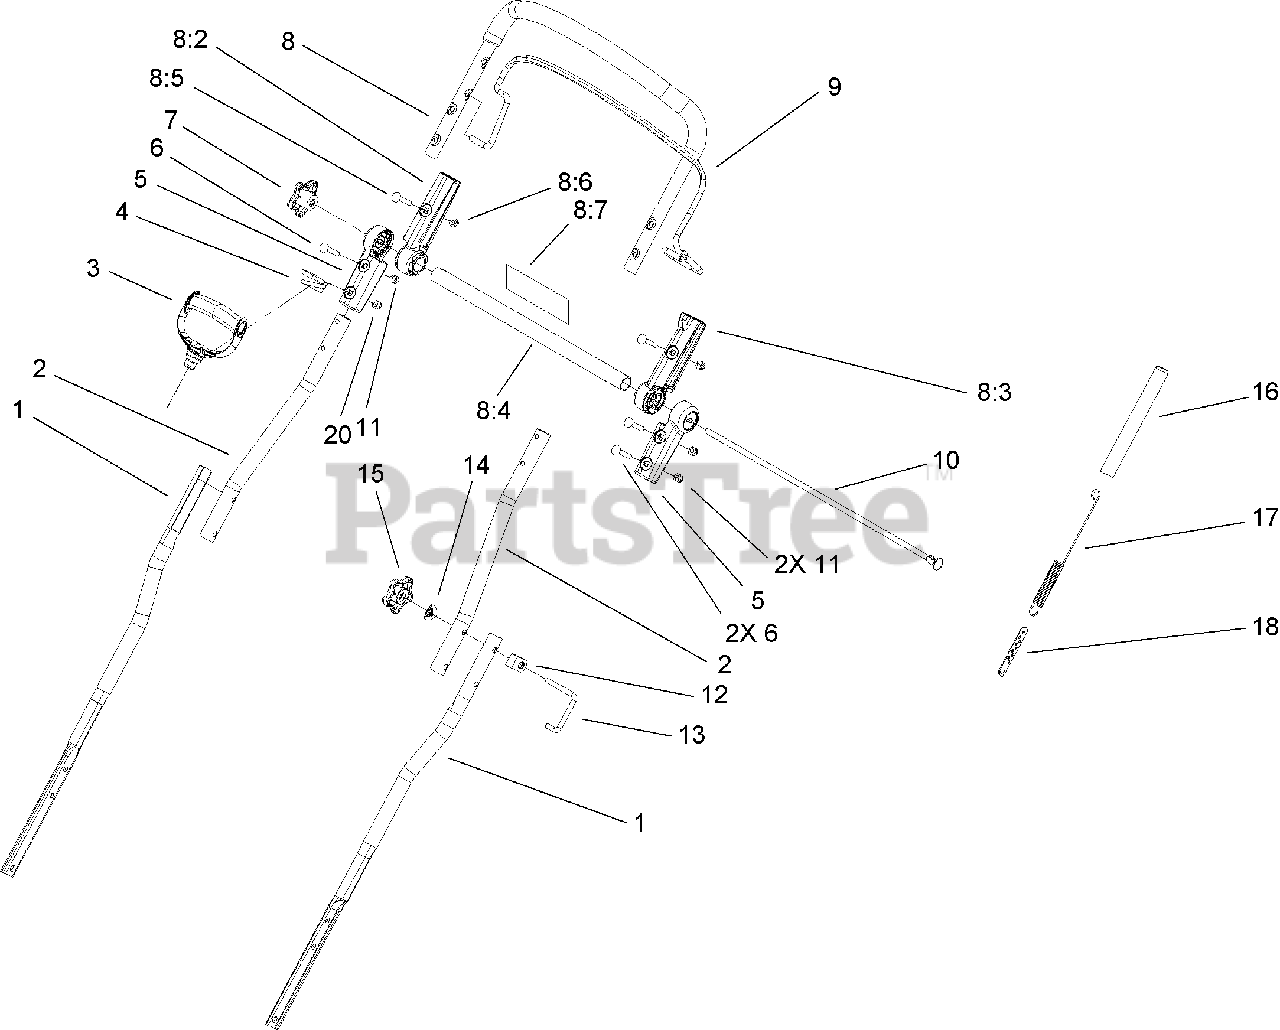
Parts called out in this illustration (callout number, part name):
1	HANDLE-LOWER
2	HANDLE-UPPER
3	HANDLE-RECOIL
4	GUIDE-ROPE
5	MOUNT-HANDLE, LOWER
6	SCREW-CARR
8	UPPER HANDLE ASM
8:2	MOUNT-HANDLE, RH
8:3	MOUNT-HANDLE, LH
8:5	SCREW-CARR
8:6	NUT-LOCK, NI
8:7	DECAL-ROTOR DRIVE/HANDLE HEIGHT KNOB
10	ROD-THREADED
11	NUT-LOCK, NI
13	LOCK-HANDLE
15	KNOB-HANDLE
16	COVER-SPRING
17	SPRING-EXTENSION
18	ADJUSTER-CABLE, CLUTCH
20	NUT-LOCK, NI
